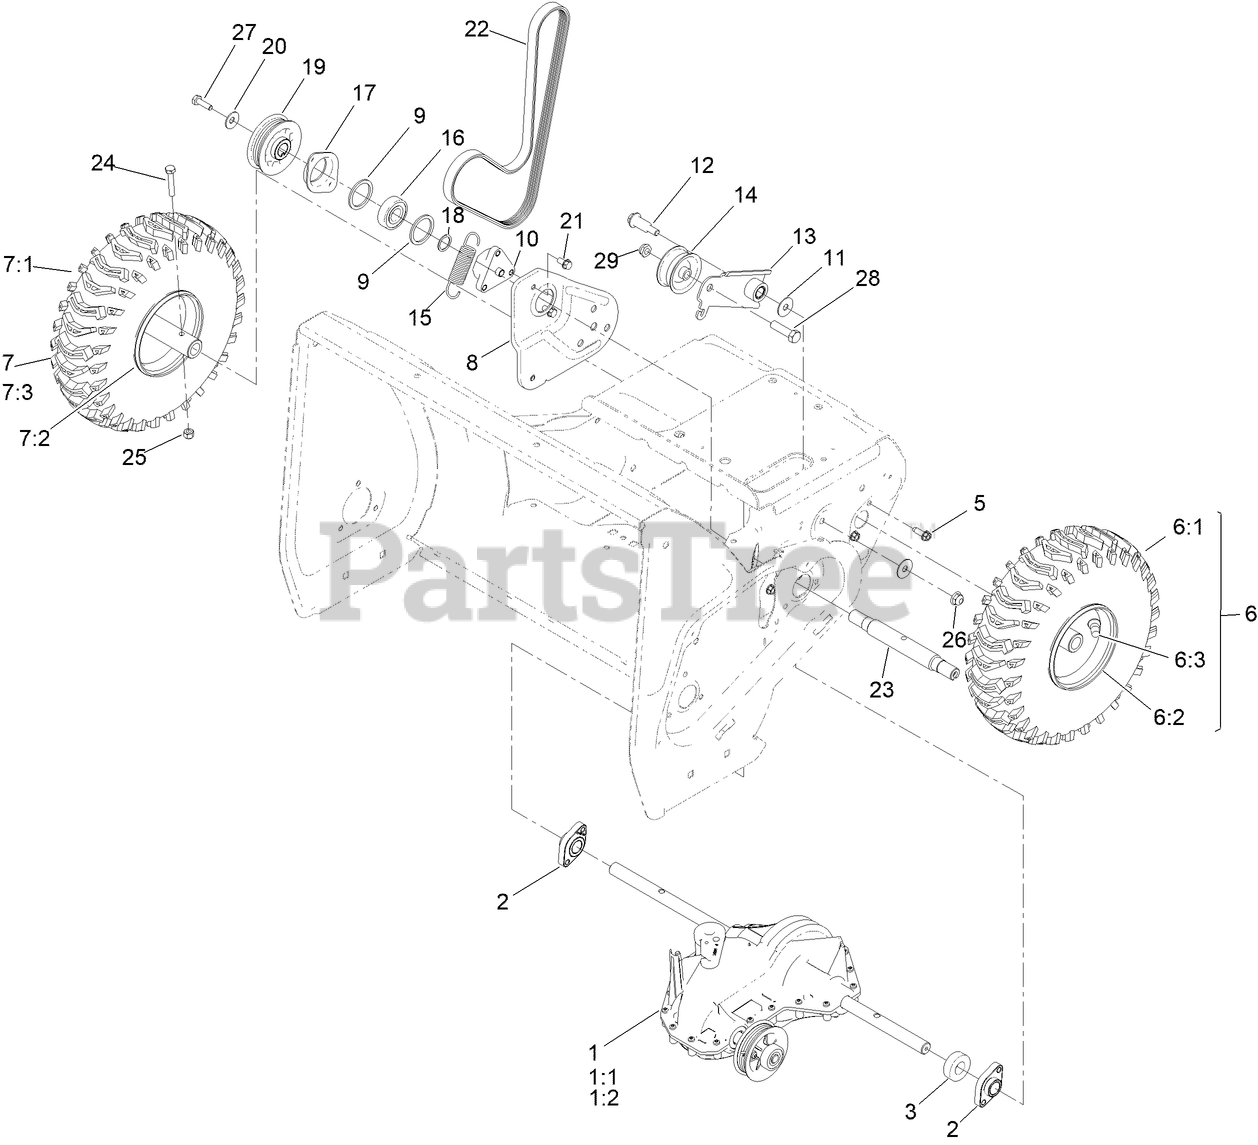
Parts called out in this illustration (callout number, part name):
1	TRANSMISSION
1:1	PULLEY REPAIR KIT
1:2	PLUG-OIL
2	BEARING-AXLE
3	SPACER-AXLE
5	SCREW-HWHTF
6	LH WHEEL AND TIRE ASM
7	RH WHEEL AND TIRE ASM
8	PLATE-SUPPORT, JACKSHAFT
9	WASHER-RUBBER
10	SUPPORT-BEARING
11	WASHER
12	BOLT-SHOULDER, HHF
13	IDLER-TRACTION
14	PULLEY-IDLER, FLAT
15	SPRING-EXTENSION
16	BEARING-BALL
17	RETAINER-BEARING
18	WASHER-THRUST
19	PULLEY-JACKSHAFT
20	WASHER-BELLEVILLE
21	SCREW-HWH
22	BELT-POLY V
23	JACKSHAFT
24	SCREW-HH
25	NUT-HEX
26	NUT-HF
27	SCREW-HH,LOCK
28	SCREW-HH
29	NUT-HEX
